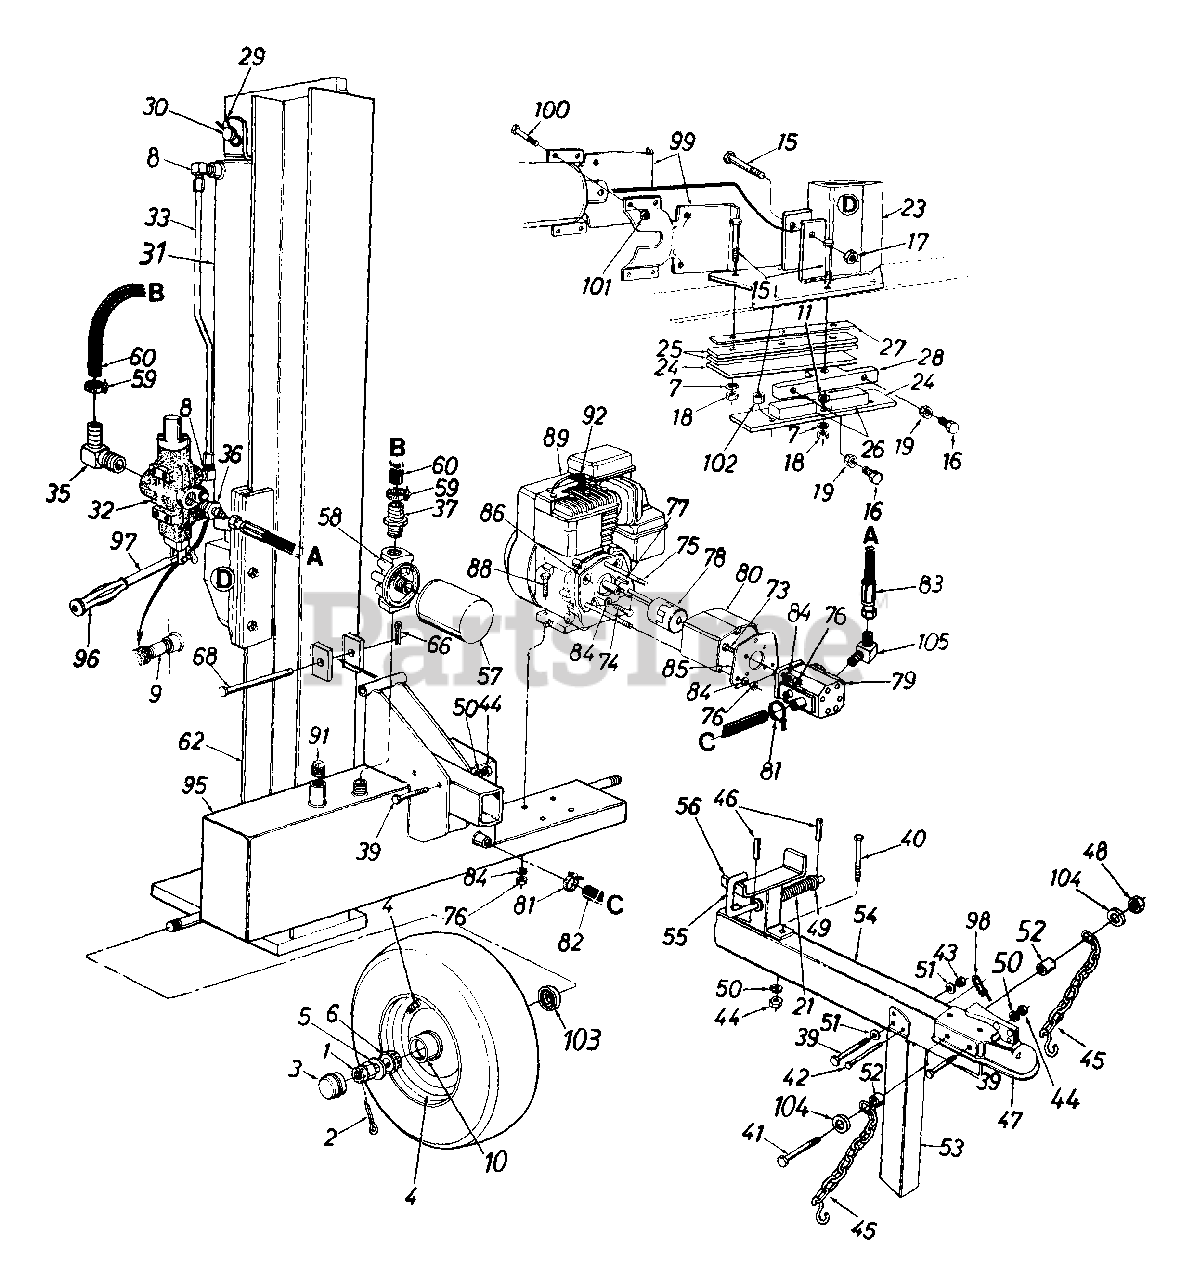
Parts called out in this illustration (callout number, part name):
1	Slotted Nut 3/4-16 Thd.
2	Cotter Pin 5/32" Dia. x 1-1/4" Lg.
3	Hub Cap
4	Wheel Ass'y. Comp.
4	Tire Only
4	Rim Only
4	Bearing Seal Only
4	Air Valve Only
5	Fl-Wash. .76" I.D. x 1.5" O.D,
6	Bearing Cone
7	L-Wash. 1/2" I.D.
8	90ø Solid Male Adapter
9	Pipe Nipple 1/2 NPT
10	Bearing Cup
11	Fl-Wash. .531" I.D. x .94" O.D.
15	Hex Bolt 1/2-20 x 2.75" Lg. (Grade 8)
16	Hex Bolt 3/8-24 x 1.5" Lg.
17	Hex L-Nut 1/2-20 Thd.
18	Hex Nut 1/2-20 Thd.
19	Hex Jam Nut 3/8-24 Thd. (Grade 5)
21	Comp. Spring 4" Lg.
23	Wedge Ass'y.
25	Fixed Side Gib
27	Adjustable Gib Shim
29	External Cotter Pin
30	Cylinder Mounting Pin
31	Hydraulic Cylinder
32	Control Valve
33	Metal Pressure Tube
35	Return Elbow
36	Adapter
37	3/4" Hose Barb.
39	Hex Bolt 3/8-16 x 2.75" Lg. (Grade 8)
40	Hex Bolt 3/8-16 x 4" Lg.
41	Hex Bolt 3/8-16 x 4" Lg. (Grade 5)
42	Clevis Pin 5/16 x 2.5" Lg.
43	Hex L-Nut 3/8-16 Thd.
44	Hex Nut 3/8-16 Thd.
45	Chain - Tow Hitch
46	Roll Pin
47	Hitch Coupler
48	Hex Ctr. L-Nut 3/8-16 Thd.
49	Fl-Wash. .635" I.D. x .93" O.D.
50	L-Wash. 3/8" I.D."
51	Fl-Wash. .406" I.D. x .75" O.D.
52	Spacer 3/8" I.D. x .625" O.D.
55	Locking Rod
57	Filter Element
58	Filter Head
59	Hose Clamp 5/8"
60	Return Hose 3/4" I.D. x 44" Lg.
68	Hinge Pin 1/2 x 4.8" Lg.
73	Hex Bolt 5/16-24 x 1" Lg.
74	Hex Bolt 5/16-24 x .62" Lg.
75	Hex Bolt 5/16-24 x 4" Lg.
76	Hex Nut 5/16-24 Thd.
77	Sq. - Key 3/16" x .75"
78	Flexible Coupling
79	Gear Pump
80	Coupling Shield
81	Hose Clamp
82	Suction Hose
83	High Pressure Hydraulic Hose
84	L-Wash. 5/16" I.D.
85	Rear Coupling Support Brkt.
86	Front Coupling Support Brkt.
88	Hex Bolt 5/16-24 x 1.75" Lg.
89	Engine
91	L-Vent Pipe Plug
92	Spark Plug Boot
95	Tank Ass'y.
97	Control Handle
98	Spring Pin
101	Hex L-Nut 3/8-16 Thd.
102	Spacer 1/2" I.D. x .68" Lg.
103	Bearing Seal Only
104	Fl-Wash. 3/8" I.D. x .87" O.D.
105	90ø Male Adapter
